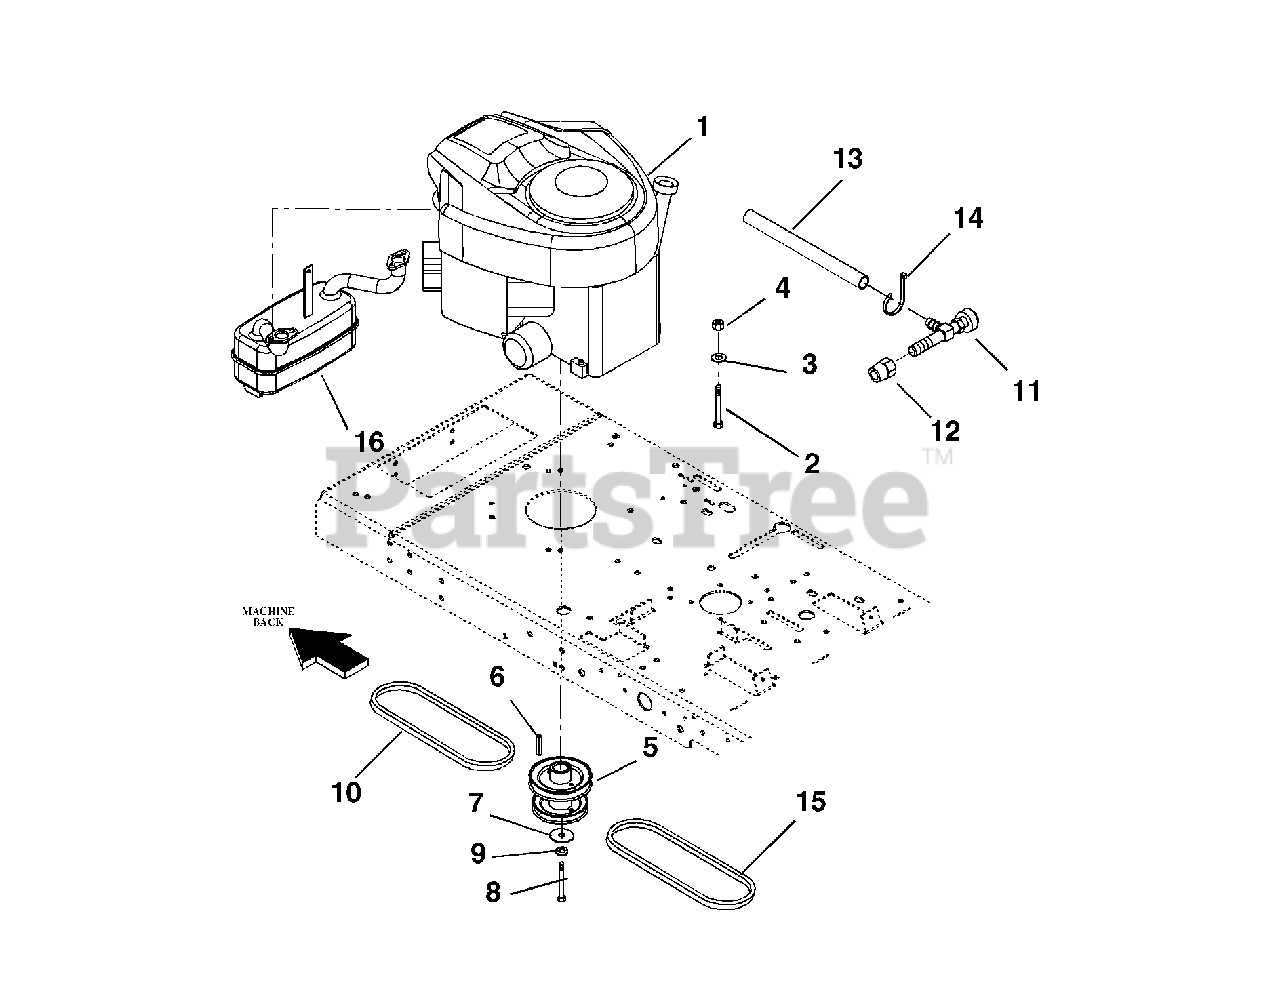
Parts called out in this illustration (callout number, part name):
1	ENGINE, B&S INTEK 20HP V TWIN
2	@BLT-HEX .31-18X1.50 GR5 YWZC
3	WSHR-FL-STL .328X1.0X.094 YWZC
4	@NUT-LK-NYL .312-18 YWZC
5	ENGINE SHEAVE 4.50
6	KEY-SQ .25 X 2.50 X .25 SAE
7	WSHR-FL-STL .469X2.00X.25 YWZC
8	BLT-HEX .44-20X3.00 GR5 YWZC
9	@WSHR-LK .44X.109 REG YWZC
10	V-BELT, 4L-RAW EDGE
11	COCK, OIL DRAIN
12	ADAPTER, OIL DRAIN
13	TUBE OIL DRAIN
14	CABLE TIE LG 5-1/2
15	V-BELT, HB-WRAPPED
16	MUFFLER ASSEMBLY
